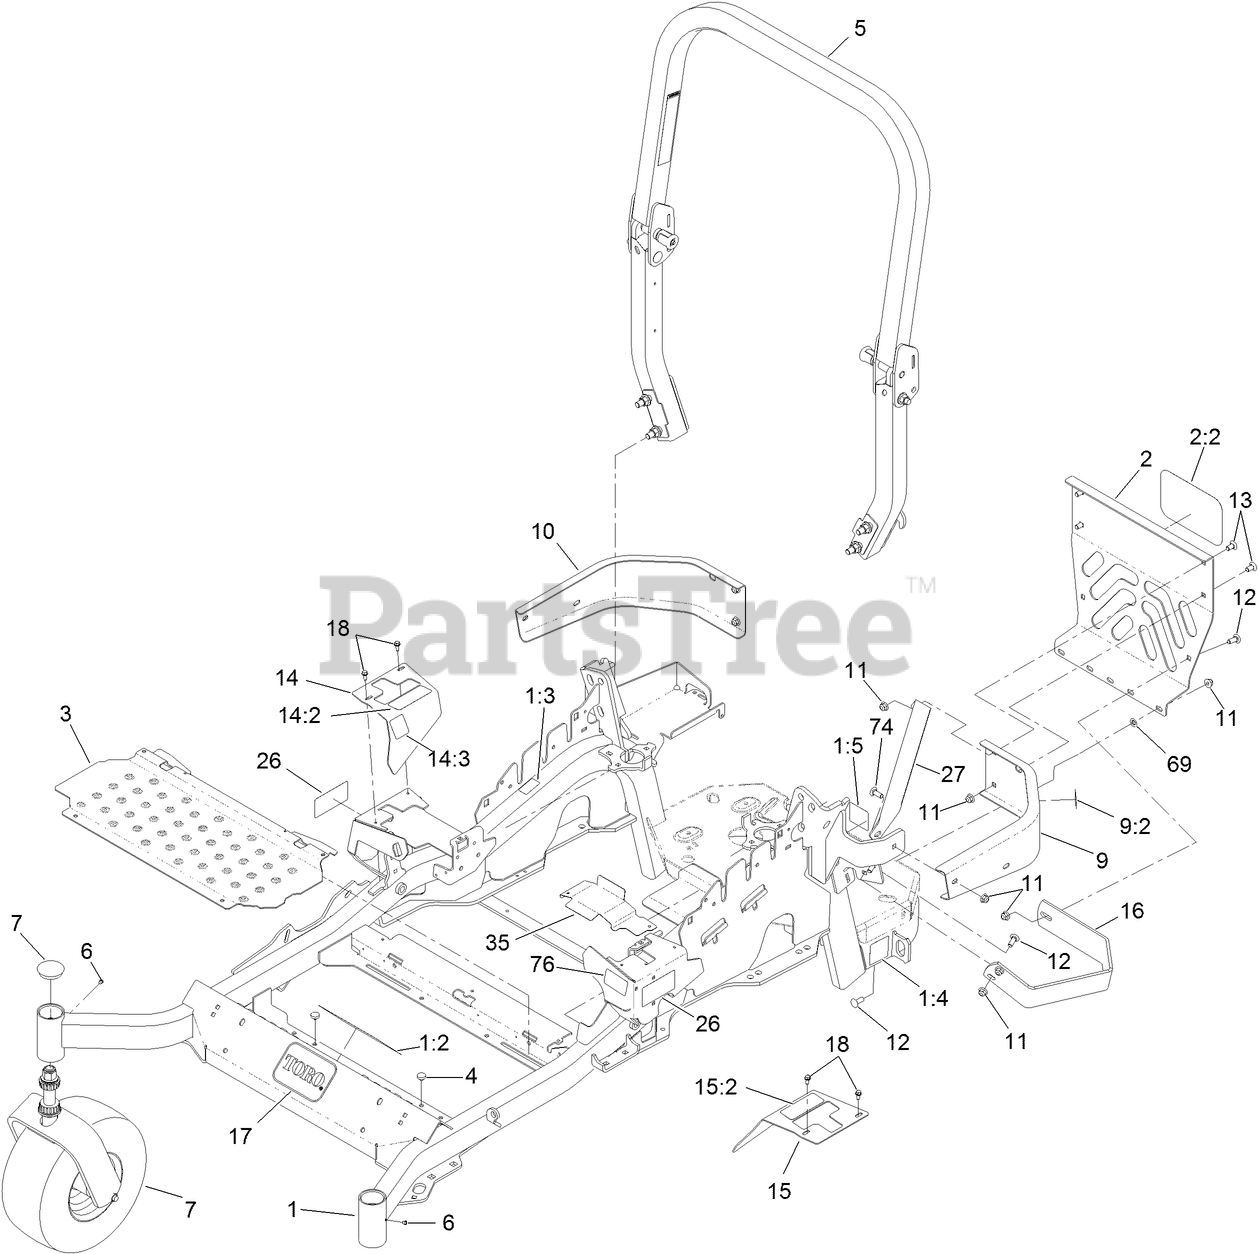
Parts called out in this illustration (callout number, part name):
1	MAINFRAME ASM
1:2	DECAL-SLOPE
1:3	DECAL-CAUTION
1:4	DECAL-BELT DRIVE
1:5	DECAL-SPARK ARRESTER
2	REAR GUARD ASM
2:2	DECAL
3	FLOORPAN
4	BUMPER
5	ROPS ASM
7	Caster Wheel ASM
9	LH BUMPER ASM
9:2	DECAL-CAUTION
10	BUMPER-RH
11	NUT-HF, NI
12	SCREW-CARR
13	SCREW-CARR
14	RH MOTION CONTROL COVER ASM
14:2	DECAL-MOTION CONTROL
14:3	DECAL-PARK BRAKE
15	LH MOTION CONTROL COVER ASM
15:2	DECAL-MOTION CONTROL
16	GUARD-MUFFLER
17	DECAL
18	SCREW-HWH
35	GUARD-BELT
69	NUT-PUSH
74	BOLT-CARR
76	DECAL-FUEL FILL
